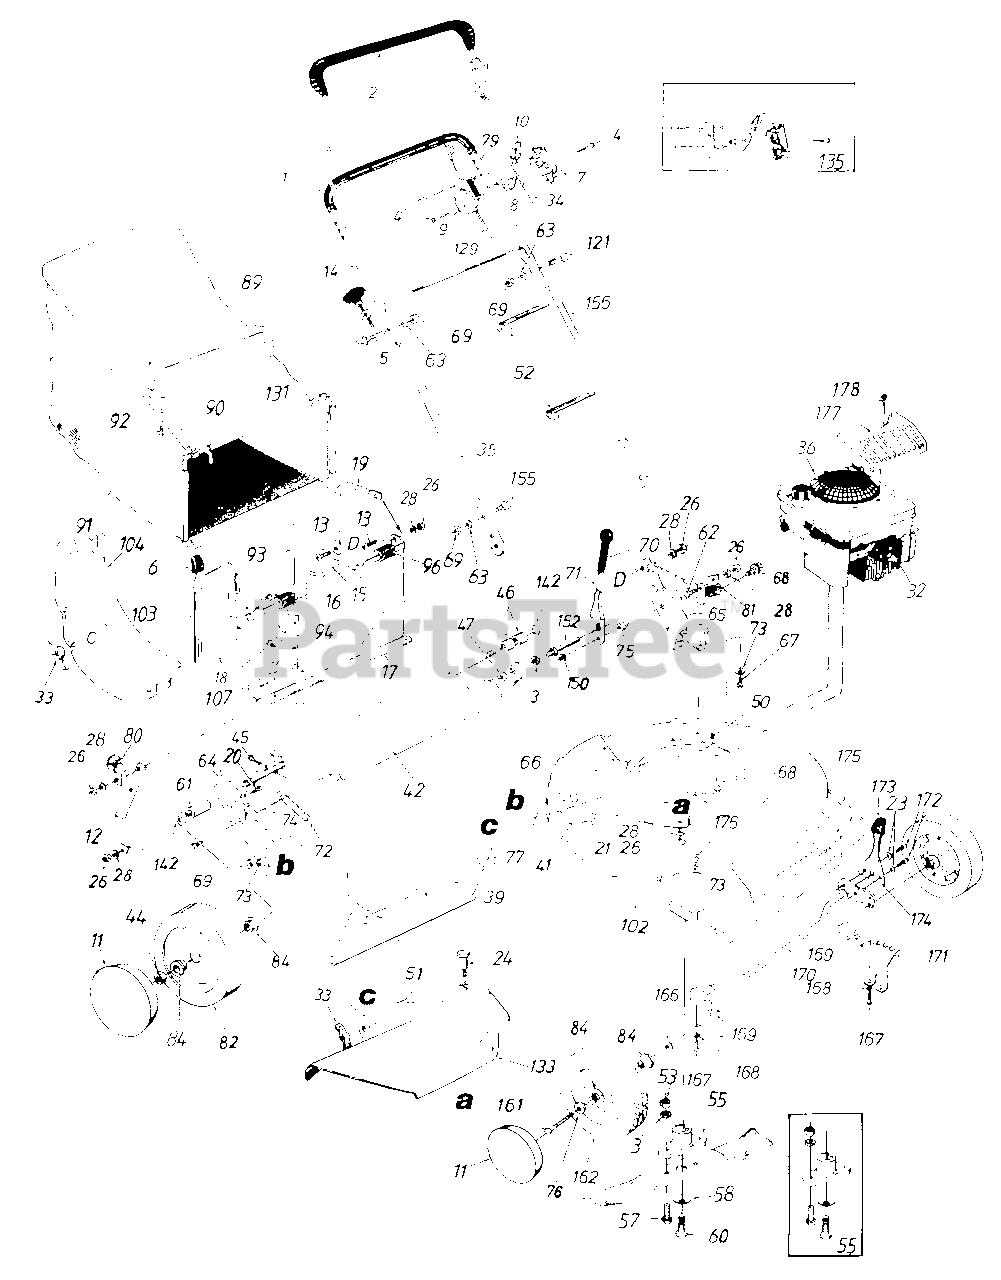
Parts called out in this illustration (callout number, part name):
1	Foam Grip
2	Control Handle Ass'y. L.H.
3	L-Wash. 3/8" I.D.
4	Truss Mach. Scr. #12 x 1.5"
5	Rope Guide Bolt
6	Door Grip
7	Control Panel Half
8	Control Disc Pin
9	Clutch Panel Half
10	Throttle Control Lever
11	Hub Cap
13	Truss Mach. Scr. 1/4-20 x .62"
14	Upper Handle
15	Foam Strip 1" Lg.
16	Truss Mach. Scr. 1/4-20 x 75"
19	Catcher Panel Support Arm
20	Hex Bolt 1/4-20 x .62" Lg.
21	Carriage Bolt 1/4-20 x .62"
23	External L-Wash. 1/4" I.D.
24	Shoulder Bolt .312 Dia. x .18 Lg. Special
26	Hex Nut 1/4-20 Thd.
28	L-Wash. 1/4" I.D.
32	Spark Plug Insulator
33	Wing Nut w/Washer
34	Throttle Control Ass'y. Comp. 61"
35	Lower Handle
36	Engine
39	Retaining Strip
41	Fl-Wash. .344" I.D. x .62"
45	Hex AB-Tap Scr. 1/4 x .62"
46	Spacer.526" I.D.
47	Hex Jam Nut 3/8-24 Thd.
51	Rear Flap
52	Cable Tie
53	Hex Nut 3/8-24 Thd.
55	Blade Adapter Kit
57	Hex Bolt 3/8-24 x 1" Lg.
58	Bell-Wash. .46" I.D. x 1.12"
60	Hex Bolt 7/16-20 x 1.5" Grade 5
61	Sleeve.526" I.D.
62	Truss Mach. Scr. 1/4-20 x .75" Lg.
63	L-Wash. 5/16" I.D.
64	R.H. Handle Wheel Brkt. Ass'y.
65	L.H. Handle Wheel Brkt. Ass'y.
66	Carriage Bolt 5/16-18 x .62"
67	Hex B-Tap Scr. 5/16-18
68	Hex TT-Tap Scr. 3/8-16
69	Hex Nut 5/16-18 Thd.
71	Height Adj. Lever
72	Extension Spring 3.80" Lg.
73	Bell-Wash. 5/16" I.D.
75	Shld. Spacer .5" Dia.
76	Wave Wash. .53" I.D. x .78"
77	Bolt Retainer 1/4 x .50" O.D.
79	Control Label
80	Rope Guide
81	Clamp
82	Wheel Ass'y. Comp.
84	Flange Ball Bearing 1/2" I.D.
89	Bag Handle
91	Grass Bag
92	Hex AB-Tap Scr. #12 x 1.25" Lg.
93	Chute Rod .188" Dia.
94	Torsion Spring
96	Panel Clip
104	Top Discharge Chute Ass'y.
107	Hex Bolt 1/4-20 x .50" Lg.
121	Curved Carr. Bolt 5/16-18 x 1.75" Lg.
129	Control Cable 46"
133	Side Chute Deflector Ass'y.
135	Kit Control Housing Comp.
142	Fl-Wash. .510" I.D. x .75"
150	Fl-Wash. 3/8" I.D. x 1.0"
152	Shld. Pin 3/8-24 x 1.43" Lg.
155	Truss Mach. Scr. 5/16-18 x .75"
156	Plastic Tubing 24" Lg.
161	Front Axle Bolt
162	Wheel Ass'y. Comp.
166	Bell-Wash. .400" I.D. x .88
167	Hex B-Tap Scr. 1/4-20
168	L-Wash. 1/4" I.D.
169	Block Bushing
172	Hex Wash. Hd. Tap Scr. 1/4-20 x .38" Lg.
173	Knob
174	Spring Lever
175	Plastic Front End
176	Truss B-Tap Scr. 5/16 x .75"
177	Engine Cover
178	Truss Hd. AB-Tap Scr. #6 x .62" Lg.
